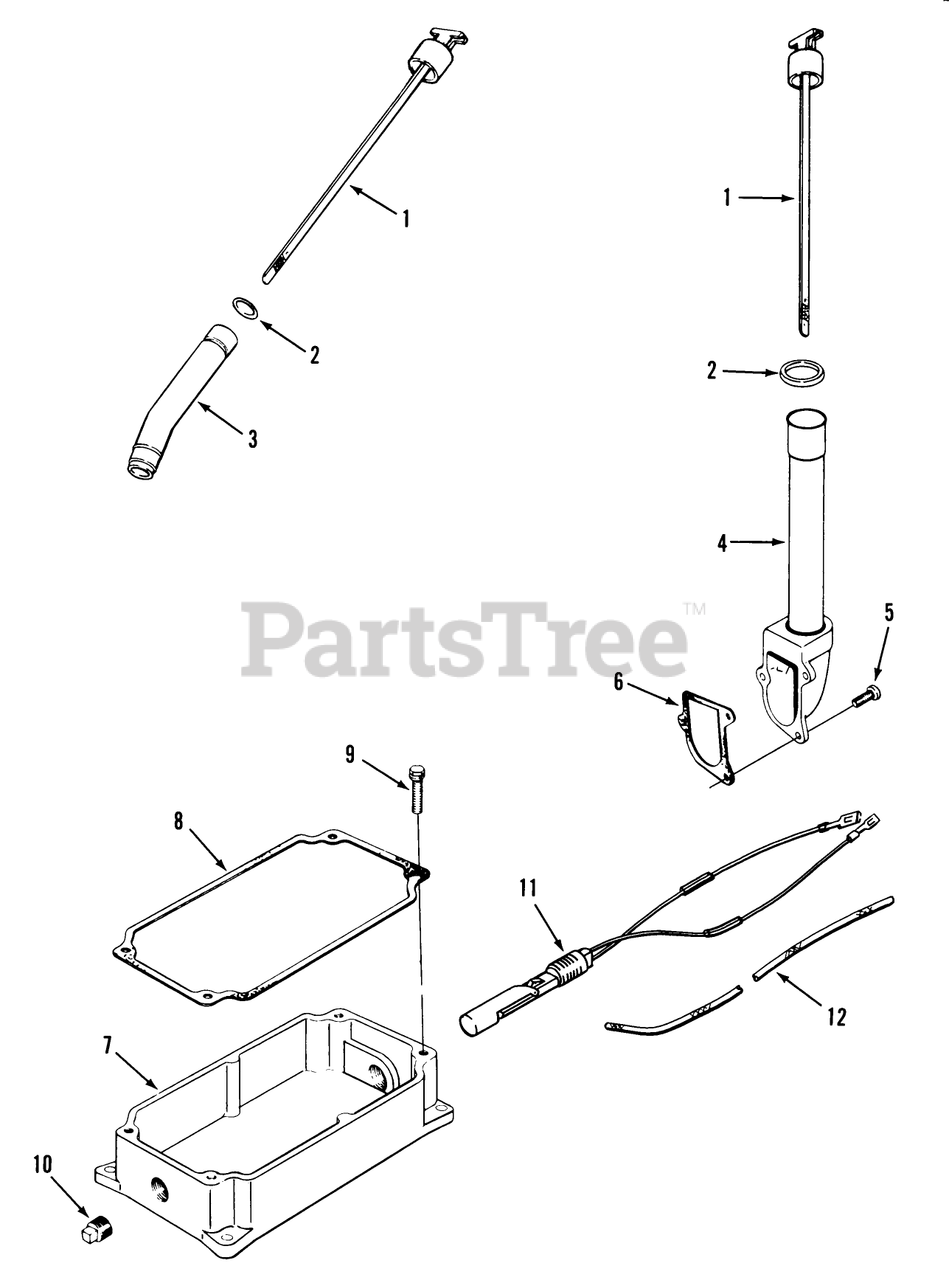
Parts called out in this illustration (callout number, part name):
1	KOHLER 41-038-14
2	KOHLER 41-153-01
3	KOHLER 41-123-19
4	KOHLER 47-029-06
5	KOHLER X-131-2
6	KOHLER 237064
7	KOHLER 41-199-01
8	KOHLER 41-041-03
9	KOHLER X-154-3
10	KOHLER X-75-28
11	KOHLER 47-099-04
12	KOHLER 25-431-02
